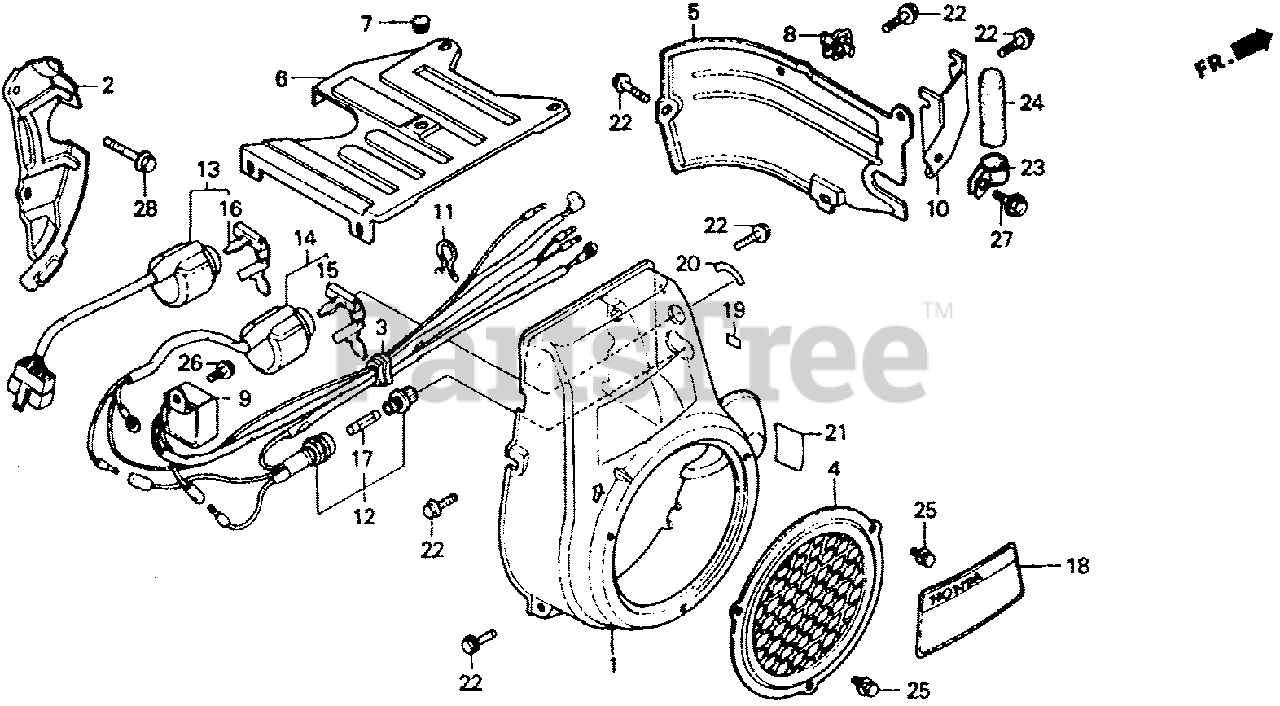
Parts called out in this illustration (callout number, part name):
1	COVER, FAN *R8* (BRIGHT RED)
2	PLATE, SIDE
3	GROMMET, SWITCH WIRE
4	PROTECTOR, FAN COVER *R8* (BRIGHT RED)
5	SHROUD
6	COVER, TOP
7	GROMMET, TOP COVER
8	CLIP, IGNITION WIRE (8MM)
9	RECTIFIER, SILICON
10	STAY, CLAMP
11	CLIP, PURSE LOCK
12	HOLDER, FUSE (1.5A) (NOT AVAILABLE)
13	SWITCH ASSY., COMBINATION
14	SWITCH ASSY., COMBINATION
15	KEY
16	KEY
17	FUSE (1.5A) (NOT AVAILABLE)
18	EMBLEM (ENGLISH/FRENCH/SPANISH)
18	EMBLEM (THAI)
19	MARK, FUSE (1.5A)
20	MARK, ENGINE SWITCH
21	MARK, OIL CAUTION
22	BOLT, FLANGE (6X12) (CT200)
23	CLIP, CORD
24	TUBE, CORD (25MM)
25	BOLT, FLANGE (6X8)
26	BOLT, FLANGE (6X10)
27	BOLT, FLANGE (6X12)
28	BOLT, FLANGE (8X20)
